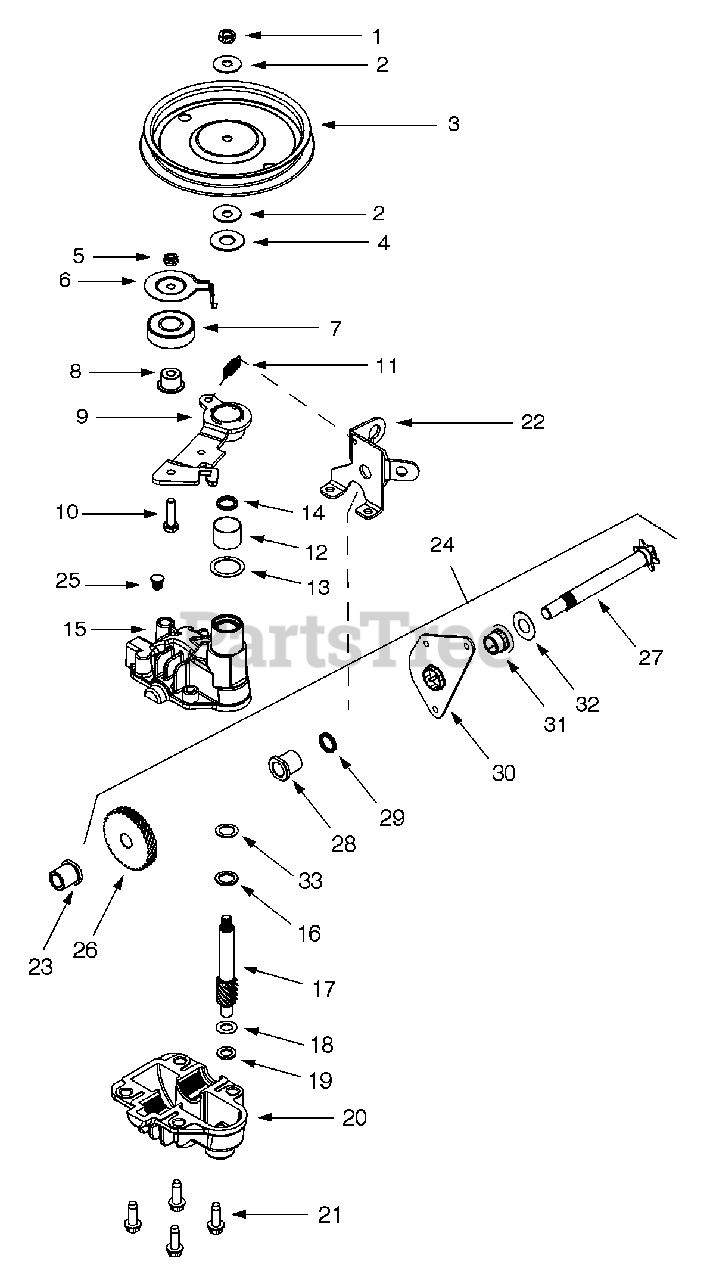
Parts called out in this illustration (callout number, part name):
1	Hx. Jam Nut, 5/16-24
2	Bell Wash. .325 x .930 x .045
4	Fl. Wash. .510 x 1.120 x .060
5	Hx. Jam Nut, 1/4-28
7	Bearing
8	Flange Spacer
9	Idler Bracket Assembly
10	Hx. Cap Scr. 1/4-28 x 1.00 Gr. 5
11	Extension Spring
12	Bearing Sleeve
13	Fl. Wash. .885 x 1.145 x .030
14	Oil Seal
15	Upper Housing Assembly
16	Thrust Wash. .504 x .700 x .030
17	Pinion Shaft, 10 T.
18	Thr. Wash. 3/8 x .70 x .030
19	Thr. Wash. .388 x .625 x .062
20	Lower Housing Assembly
21	Hx. Scr. 1/2-20 x .75
24	Shaft Assembly
27	Output Shaft, 6 T.
28	Flange Bearing
29	Oil Seal
30	Pivot Bracket
31	Flange Bearing
